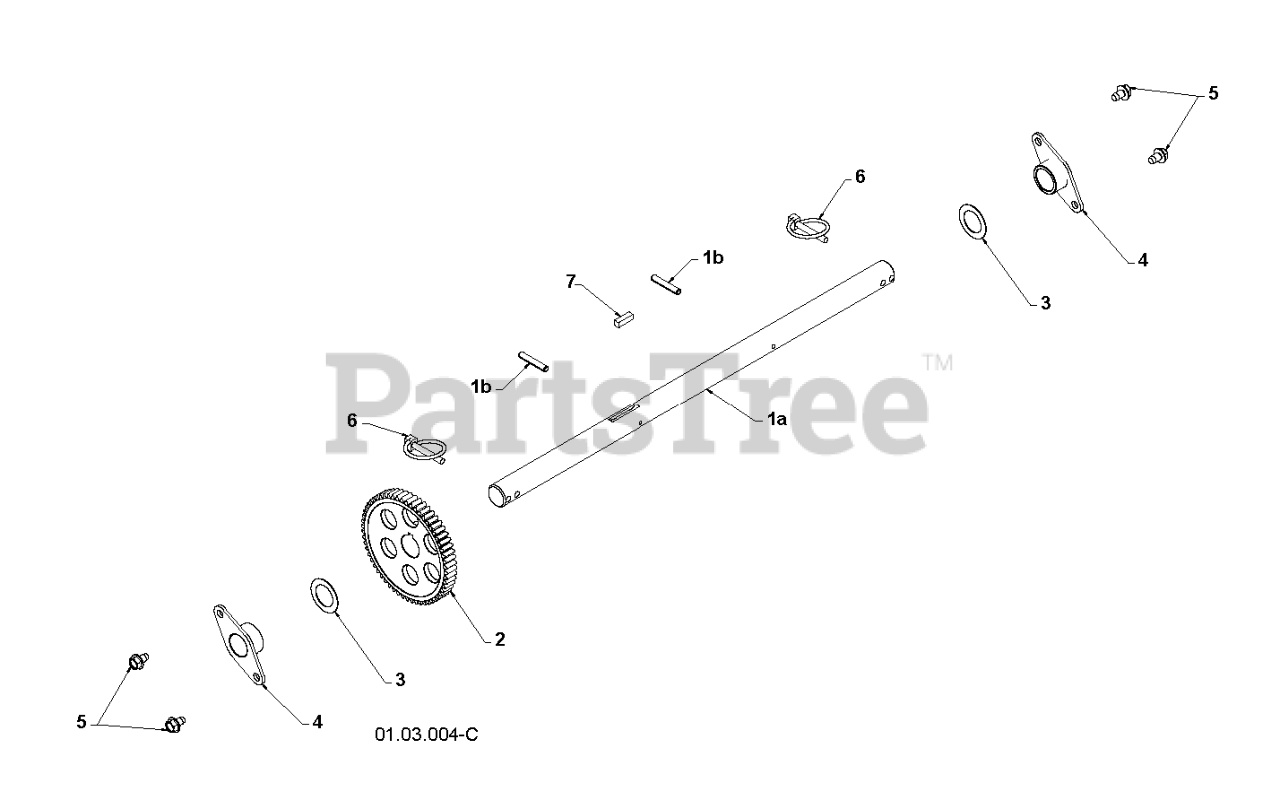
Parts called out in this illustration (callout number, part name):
1	AXLE.SHAFT.ASM.W/ROLPIN.NON-PS
2	SPROCKET.WELDMENT.AXLE.1.00
3	WASHER TRUST 1"
4	BEARING, AXLE
5	Screw 5/16-18 x 1/2 Hex, Self Tapping 5/16-18 x 1/2
6	RIVET
7	KEY, SQUARE 1/4 X .875
8	RETAINER M
